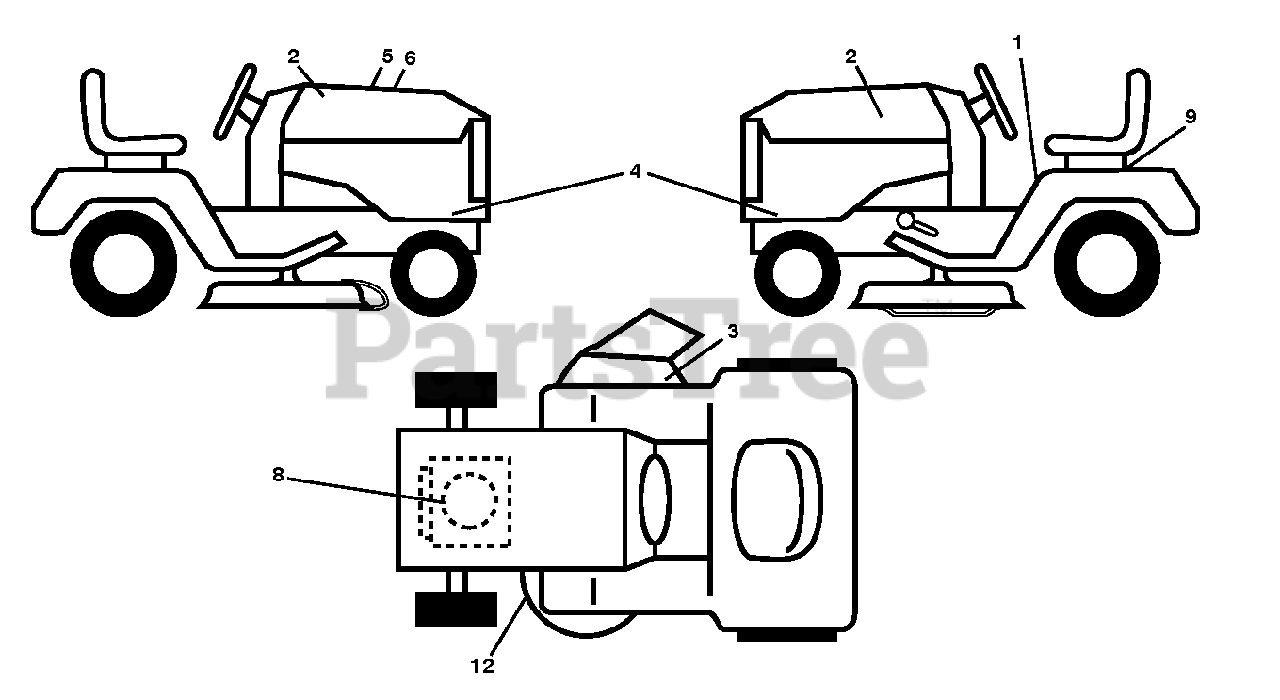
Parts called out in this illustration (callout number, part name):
1	DECAL.FENDER.WARNING
2	RP.DECAL.BADGE.170MM.TEXTLOGO
3	DECAL.WARN.KEEP.HAND.AWAY
4	DECAL.SDPNL.HUSGT2.YTH2042.
5	DECAL.WARNING.CUST.RESP.E85.
6	DECAL RPL.BSM33.INT.TLW.42.K46
8	Decal, Engine BS 20HPXRD
9	DECAL BTRY SYMBOLS
12	DECAL V BELT SCHEMATIC
